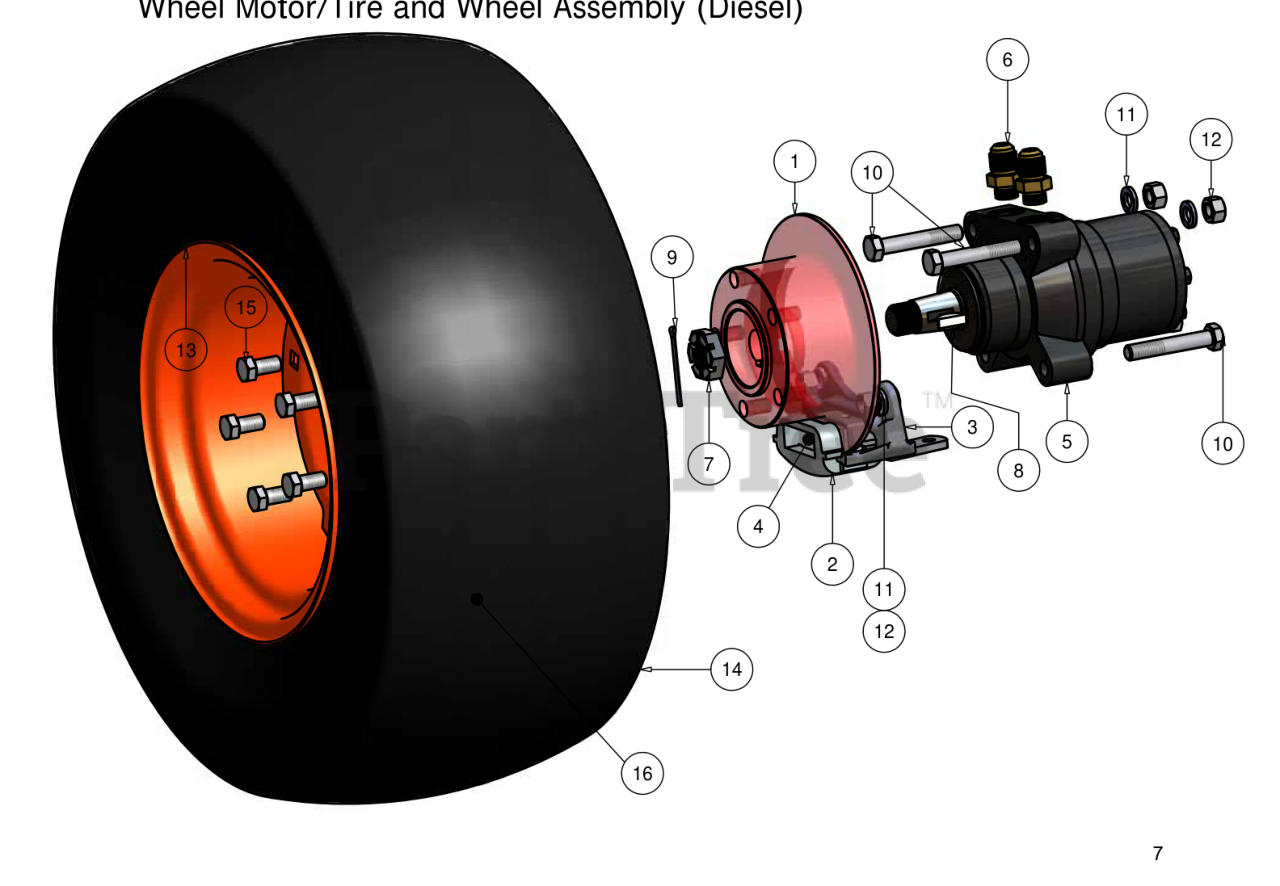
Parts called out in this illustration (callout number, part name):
1	Brake Disc
2	Right Brake Assembly
2	Left Brake Assembly
3	Brake Casting
4	Brake Pads
5	Right Wheel Motor
5	Left Wheel Motor
6	3" Hydraulic Fitting
7	Castle Nut
8	Woodruff Key
9	1/8" x 2 1/4" Cotter #8
10	1/2" x 3" Hex Bolt
11	1/2" Lock Washer
12	1/2" Hex Nut
13	12" Rim AOS Models -
14	26x12-12 Tire - AOS Models
15	1/2" x 1" Lug Bolt (Fine Thread)
16	26 x 12-12 Tire and Wheel Assembly
